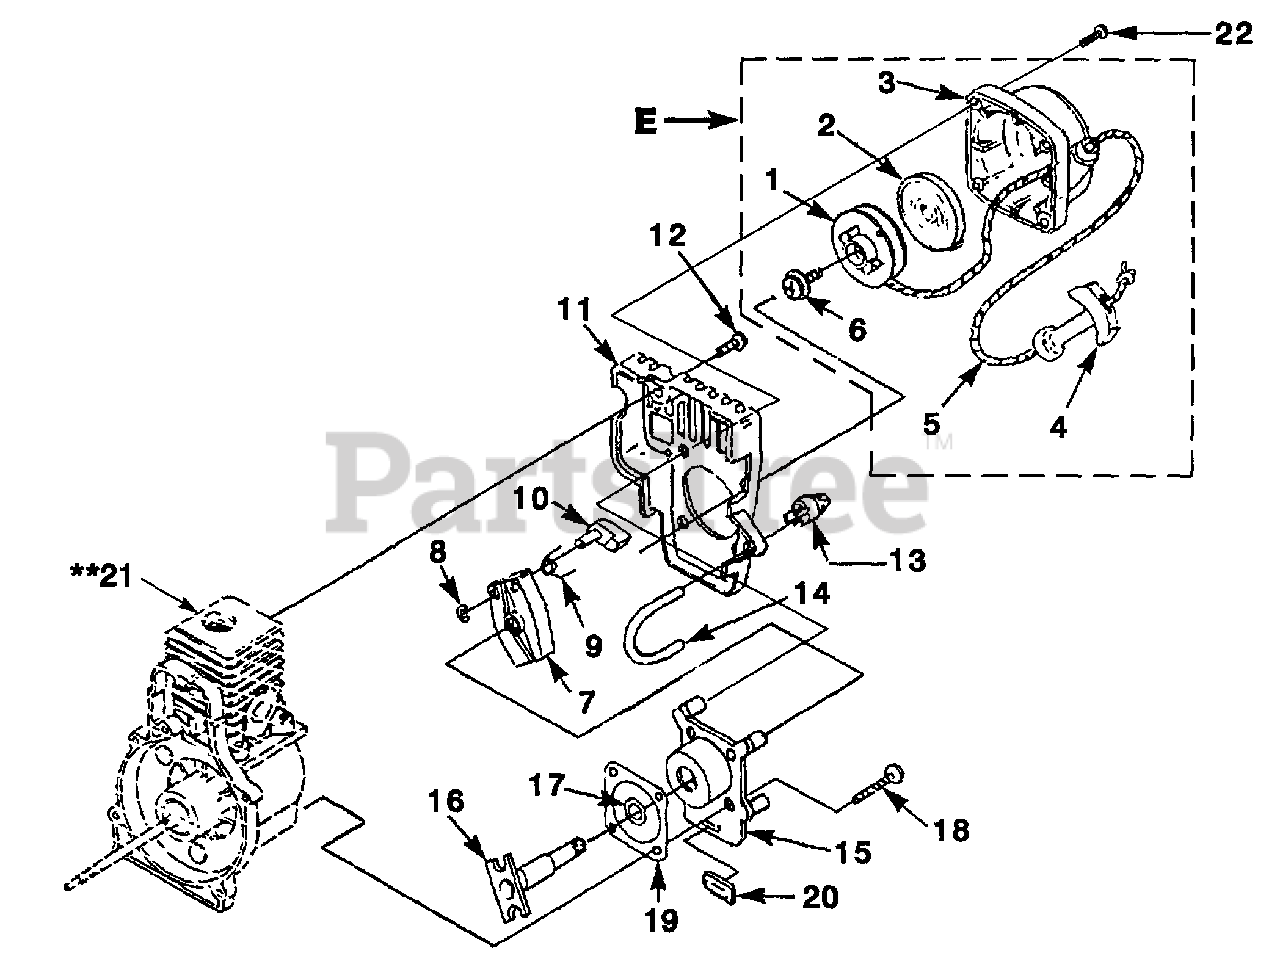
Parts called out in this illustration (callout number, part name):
1	PULLEY-Starter
2	SPRING-Recoil
3	HOUSING-Starter
4	GRIP-Starter
5	ROPE-Starter
6	SCREW-Set
7	CUP-Starter
8	RETAINING RING
9	SPRING-Starter
10	PAWL-Starter
11	COWLING-Engine
12	SCREW-Thread Forming (#10 X 1/2")
13	BULB-Air Purge
14	RUBBER TUBING (8")
15	CRANKCASE COVER
16	SHAFT-Starter
18	SCREW-Thread Form. (10-24 X 3/4")
19	GASKET-Crankcase
20	BUMPER-Rubber
21	SHORT BLOCK
22	SCREW-Taptite, T-25 Torx (10-24 X 3/4")
E	STARTER-Complete
